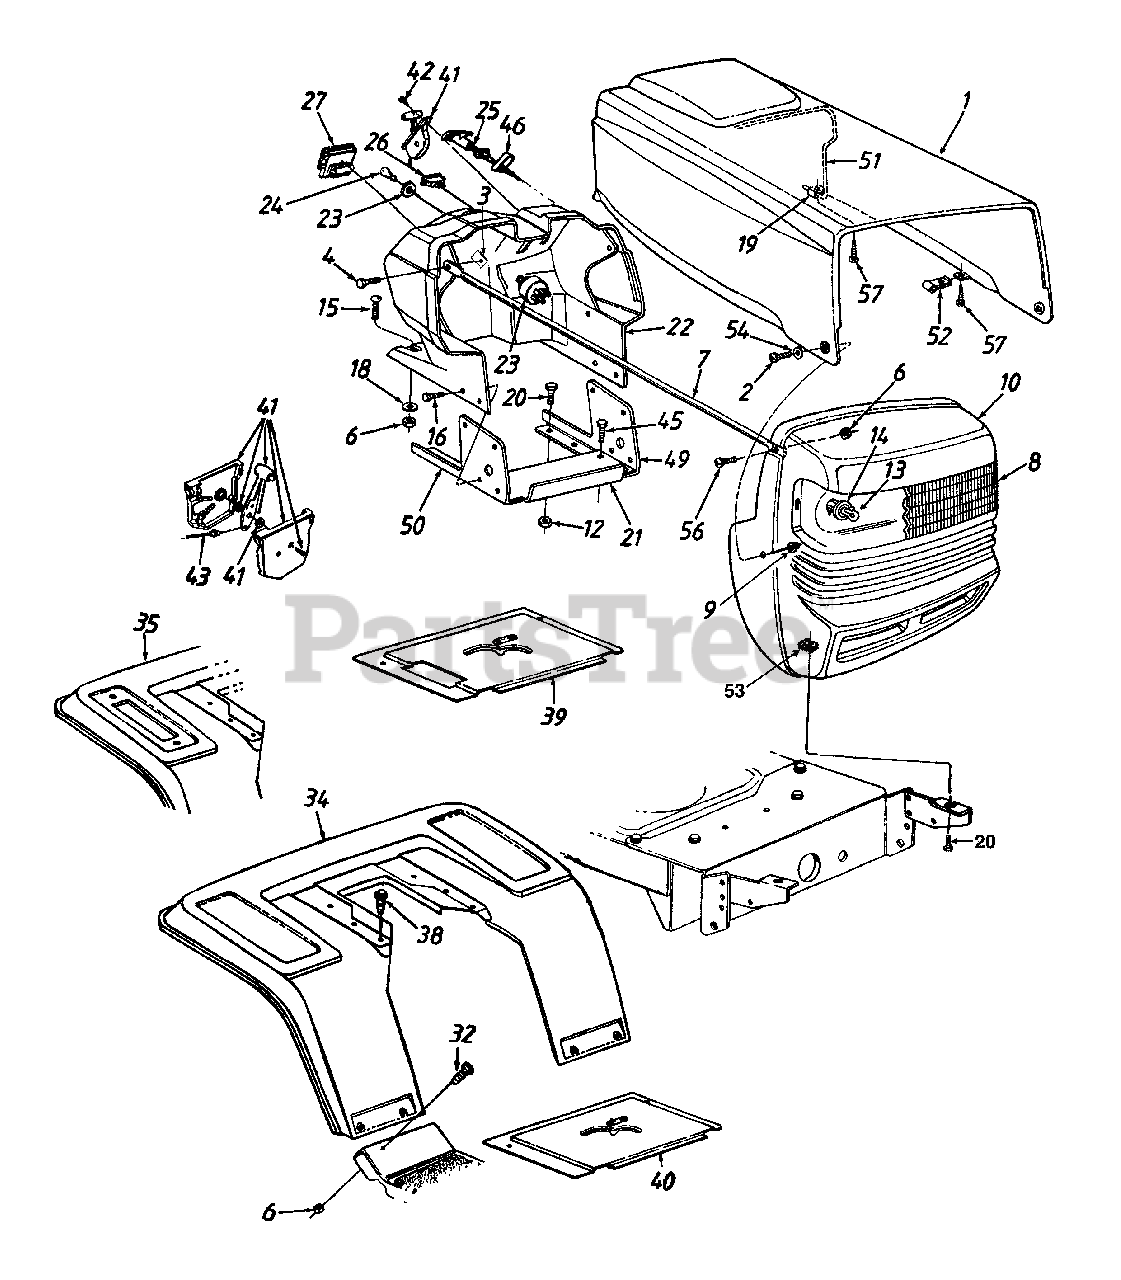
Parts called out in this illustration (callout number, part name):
3	Speed Nut 1/4-20 Thd.
4	Hex Bolt 1/4-20 x .88" Lg.
6	Hex Sems Nut 1/4-20 Thd.
9	Flange L-Nut 1/4-20 Thd.
12	Hex Sems Nut 5/16-18 Thd.
13	Lamp
14	Socket
15	Carriage Bolt 1/4-20 x .75" Lg.
16	Hex Wash. Hd. TT-Tap Scr.1/4-20 x .5"
18	Bolt Retainer 1/4" I.D.
19	Speed Nut #10-24 Thd.
20	Hex Bolt 5/16-18 x .1" Lg. (Gr.5)
23	Ignition Switch
24	Ignition Key
25	Choke Control 23" Lg.
26	Light Switch
27	Ammeter
32	Truss Mach. Scr. 1/4-20 x .5" Lg.
41	Throttle Box Ass'y.
42	Truss Mach. AB-Tap Scr.#10 x .5"
43	Throttle Control Wire 18.5" Lg.
45	Hex Wash. B-Tap Scr.5/16-18 x .5"
46	Choke Retainer
52	Flat Fastener (Special)
53	U-Nut 5/16-18 Thd.
54	Spr. Wash. .39" I.D. x .62" O.D.
56	Pan Hd. Scr. 1/4-20 x .75" Lg.
57	Truss Mach. Scr. #10-24 x .5" Lg.
